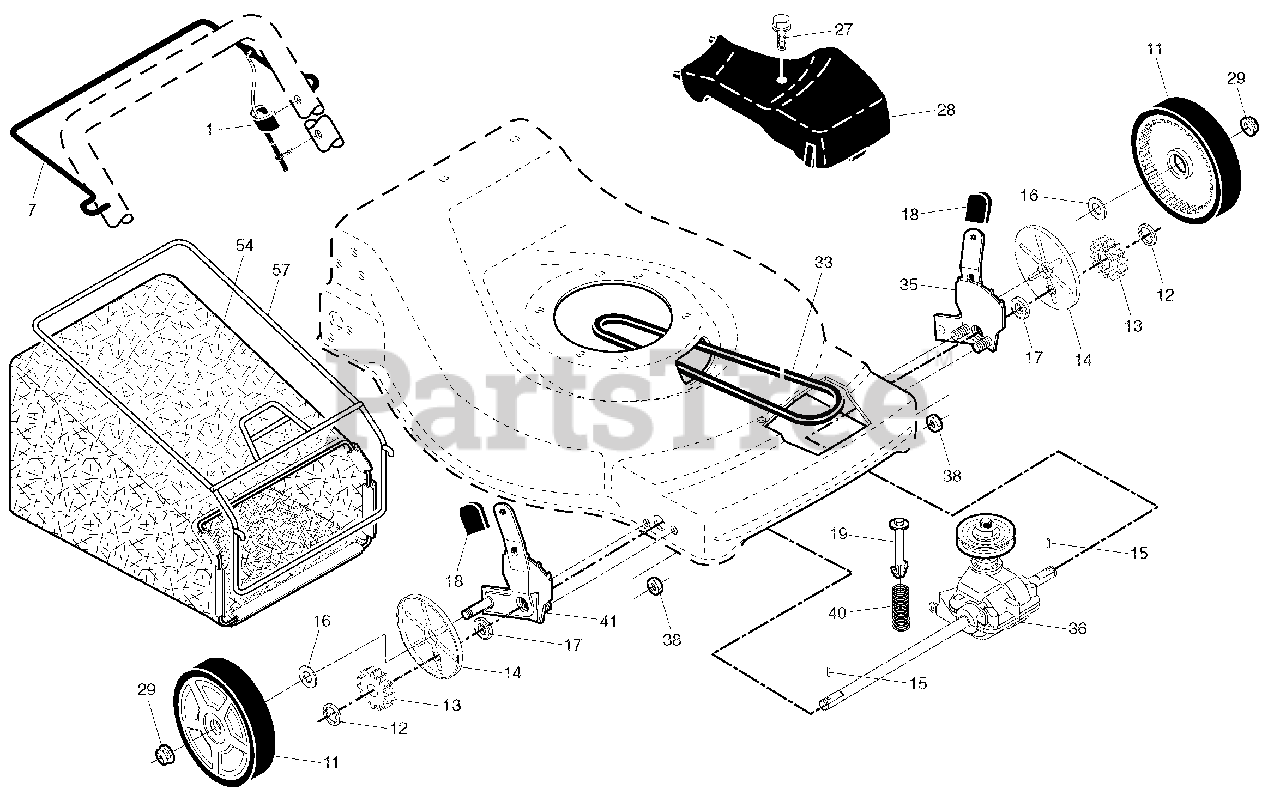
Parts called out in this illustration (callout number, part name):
1	CABLE, DRIVE CONTROL
7	Control Bar, Drive
11	WHEEL AND TIRE ASSEMBLY-FRONT
14	Dust Cover
15	Pawl, Drive
16	Washer, Flat 3/8
17	WHEEL BEARING
18	Selector Knob
19	Retainer, Spring
27	Pan Head Tapping Screw #10-24
28	DRIVE COVER
29	Nut, Hex
33	DRIVE BELT
35	Kit, Wheel Adjuster, LH
36	Gear Case Assembly, Complete
38	Flanged Locknut, Hex
41	HEIGHT ADJUSTOR
57	BAG FRAME
